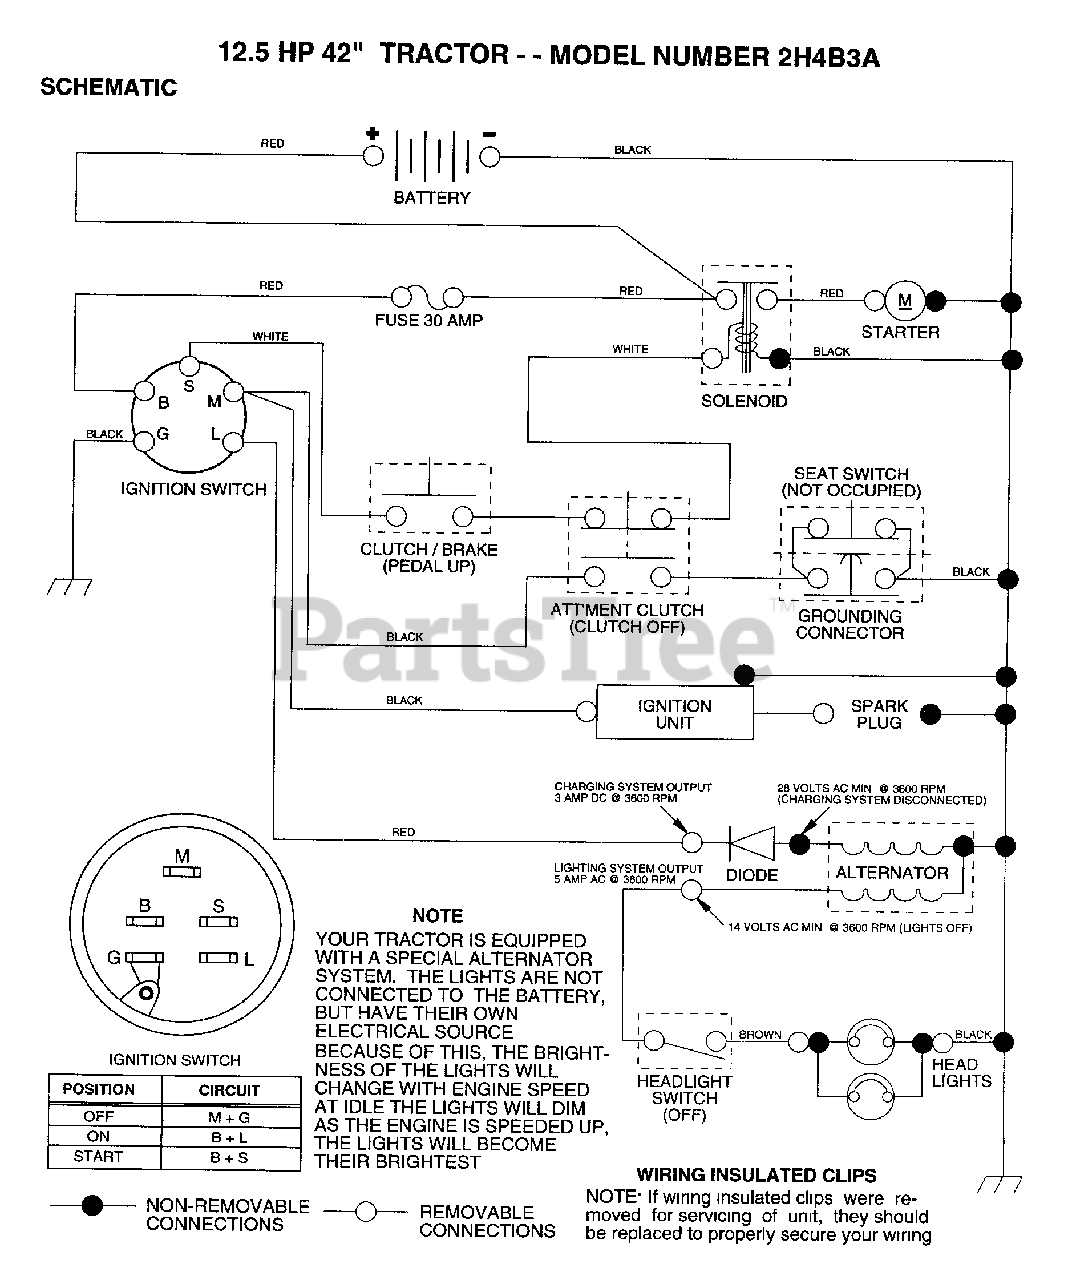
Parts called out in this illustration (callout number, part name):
4	"SPRING, DETENT LT"
5	"SCREW, SET LT"
6	KIT SHIFTER ASM
7	SHIFTER BOOT
8	SCREW TAP W/SEAL
9	SQUARE RING
10	RETAINING RING LT
11	ASM KIT SHIM 4689
12	"FLANGE, BEARING"
13	WASHER T
14	WOODRUFF KEY
15	AS KIT INPUT SHFT
16	PINION 14T T
17	"RING,RETAINING LT"
18	"CHAIN,24 PTCH LT"
19	BEARING.FLNG.5510
20	GEAR SPUR 14T
21	COLLAR CLUTCH
22	ASM KIT CLTCH KEY
23	NUT.LOCK.5/16-24
24	SHAFT INTERM
25	WOODRUFF KEY
26	"RING,RETAINING LT"
27	SPROCKET 18T T
28	SPACER YT
29	KIT.GEAR.12/37TH
32	GEAR 25T LT
33	GEAR SPUR 22 TT
34	SPUR GEAR 19T
35	"WASHER, PLAIN LT"
36	WASHER 025
37	SPACER
38	ASSM GEAR COMB
39	SHAFT IDLER
40	SPACER T
41	SPROCKET 9T LT
43	ASM KIT SHIM
44	SHAFT T
48	"GEAR, SPUR 25T LT"
49	GEAR 28T T
50	"GEAR, SPUR 31T LT"
51	WASHER 060
52	NEOPRENE WASHER
53	WASHER 031
55	GEAR 15T T
56	"RING,RETAINING LT"
58	SHAFT T
59	GEAR 1ST T
62	PUCK T
63	BRAKE DISC. T
64	SPACER LT
66	PIN T
69	WASHER LT
71	"SCREW, TAPPING LT"
72	PUCK T
